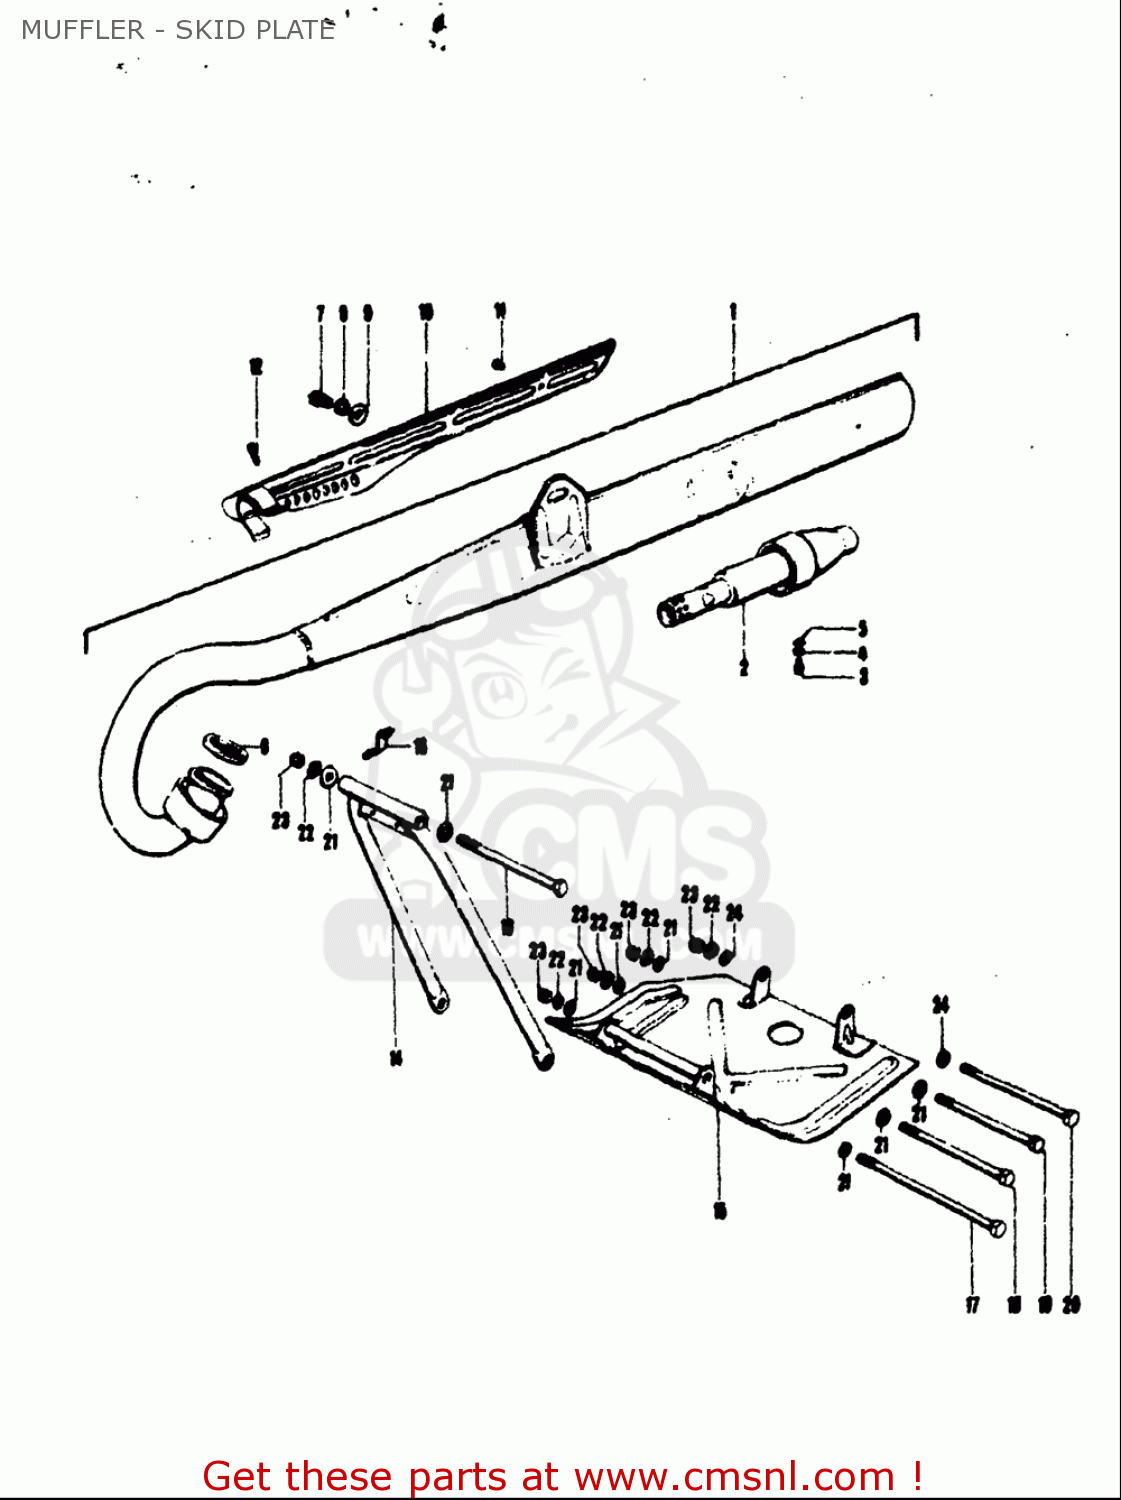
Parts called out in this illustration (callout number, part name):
4	WASHER,LOCK
5	WASHER
6	GASKET,EXHAUST (NAS)
7	BOLT
8	WASHER,LOCK
9	WASHER
12	SCREW
18	BOLT(8X115)
20	BOLT 8X125
21	WASHER
22	WASHER,LOCK
23	NUT
24	WASHER
